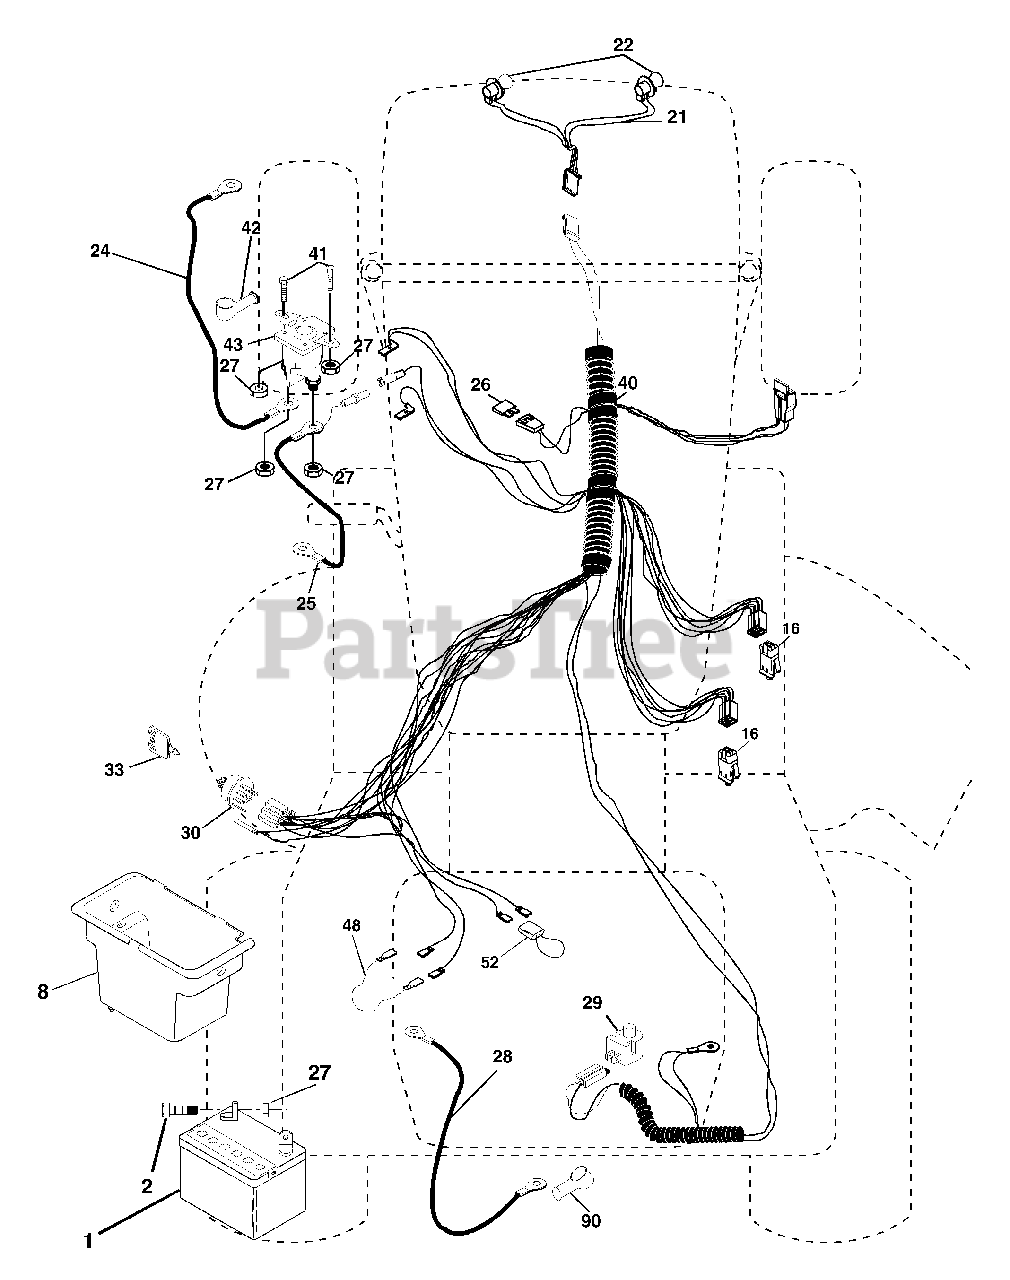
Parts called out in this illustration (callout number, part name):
1	Battery
2	Bolt Hex Hd 1/4-20 Unc x 3/4
8	Box Battery
16	Switch Interlock
21	Harness Asm Light W/4152j
22	Bulb Light #1156
24	Cable Battery 6 Ga 11" red
25	Cable Battery 6 Ga 44" red w/16 wire
27	Nut Keps Hex 1/4-20 Unc
28	Cable Ground 6 Ga 12" black
29	Switch Plunger Gray
30	Switch Ign Delta
33	Key Ign Molded Generic
40	Harness Ign.
41	Bolt Blk Fin Hex 1/4 - 20 x 1/2
42	Cover Terminal Red
43	Solenoid
48	Adapter Ammeter Rectangular
52	Protection Wire Loop
90	Cover Terminal Battery
